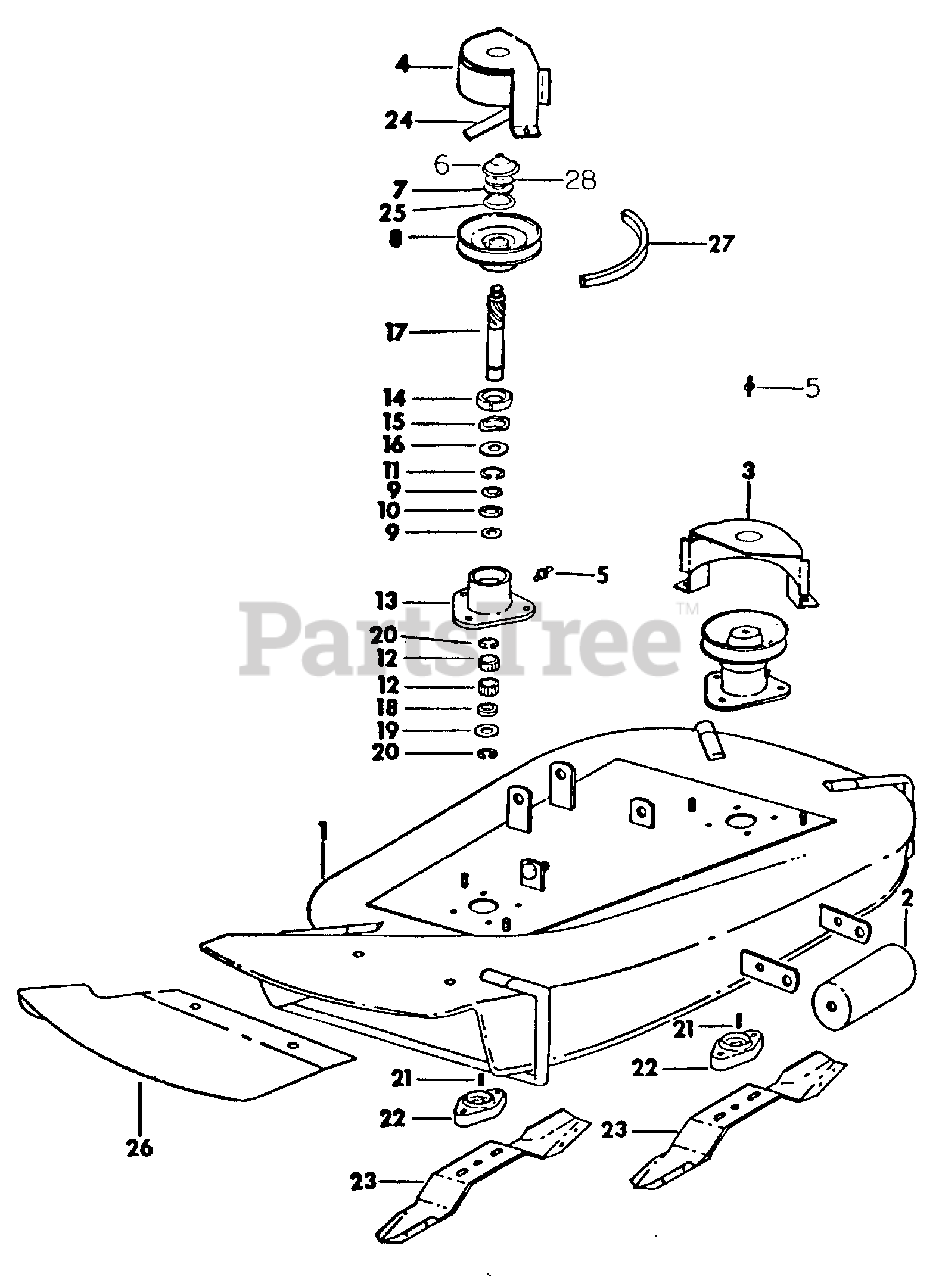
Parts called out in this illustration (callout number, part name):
1	Housing Assy, Mower
5	Fitting, 3/16 Str Drive Lube
6	Cup, Seal
7	Washer, Special
8	Pulley, Outer
9	Race, Needle Thrust Bearing
10	Bearing, Needle
11	Ring, 1-1/4 Internal Retaining
12	Bearing, Needle
13	Housing, Blade Shaft
14	Brake, Insert
15	Washer, Wave
16	Washer, Stop
17	Shaft, Blade
18	Seal, Oil
19	Washer, Thrust
20	Ring, 3/4 External Retaining
21	Key, 3/16 X 1/2 Sq Parallel
22	Adapter, Blade
23	Blade, 36 Inch Mower
24	Not used in this application
25	Not used in this application
26	Package, 36 Inch Mower Deflector
27	Belt, Mower Drive, 1/2 X 68.5 Inch Effective Length
28	Washer, .906 X 1.25 X .027 Znd
